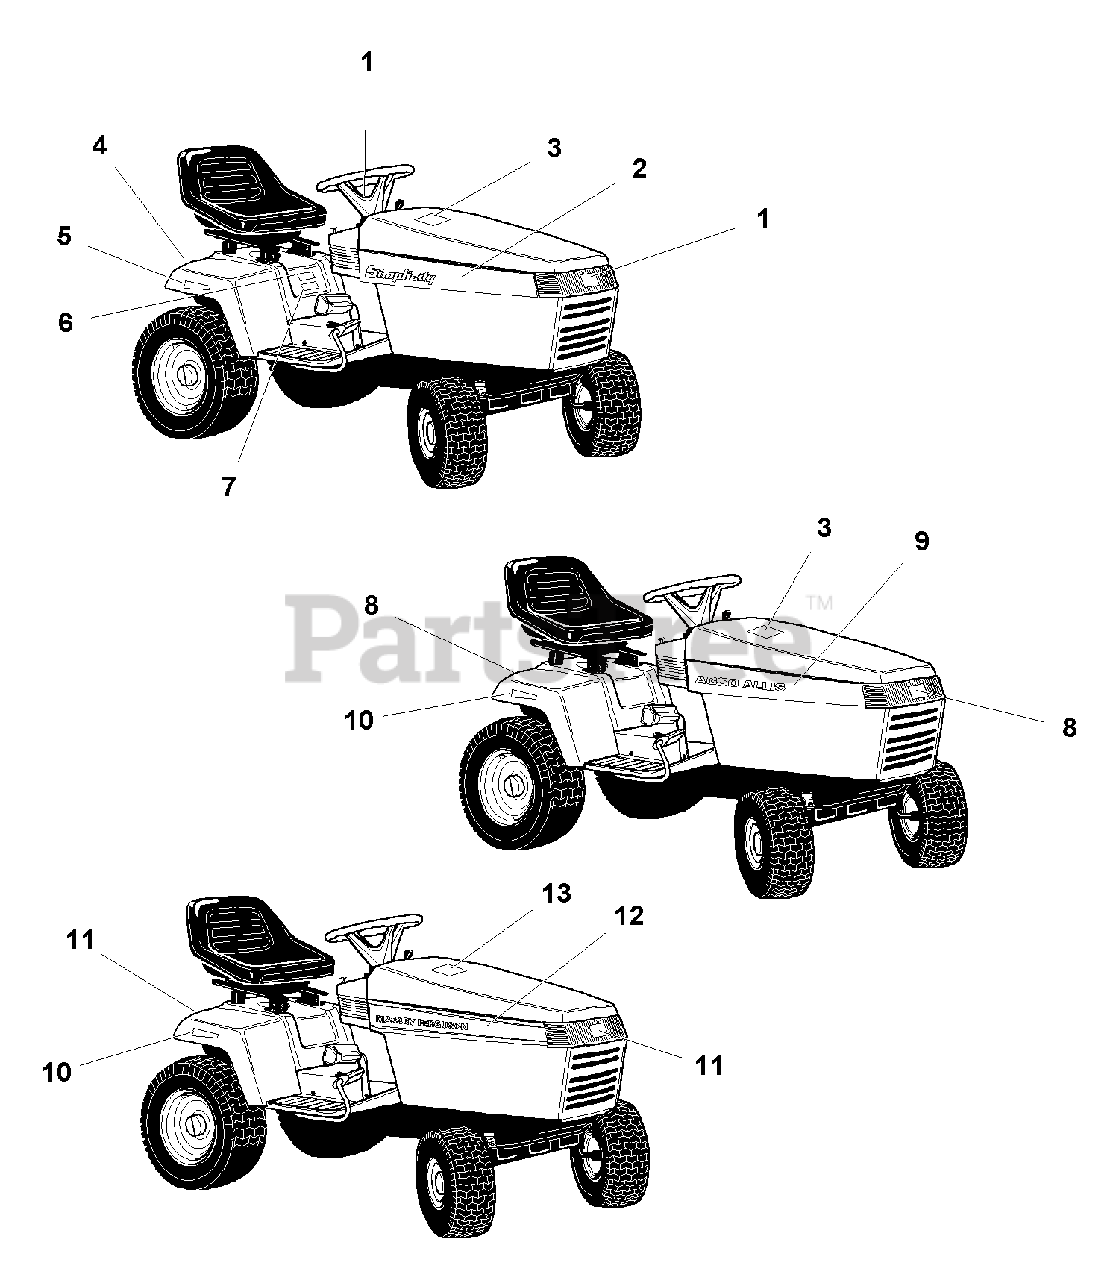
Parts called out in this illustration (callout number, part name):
1	DECAL, Simplicity Icon
2	DECAL, RH Hood, Simplicity
2	DECAL, LH Hood, Simplicity
3	DECAL, Paint, Simplicity & AGCO-Allis
4	DECAL, Simplicity Logo with Icon
5	DECAL, Controlled Traction, Simplicity
6	DECAL, Seat Deck, Broadmoor, Simplicity
7	DECAL, Model, Simplicity Broadmoor - Hydro 16 HP
7	DECAL, Model, Simplicity Broadmoor - Hydro 14V-Twin
7	DECAL, Model, Simplicity Broadmoor - Hydro 16V-Twin
7	DECAL, Model, Simplicity Broadmoor - Hydro 18V-Twin
8	DECAL, AGCO-Allis Icon
9	DECAL, LH Hood - AGCO-Allis 1615H
9	DECAL, RH Hood - AGCO
9	DECAL, LH Hood - AGCO
9	DECAL, RH Hood - AGCO-Allis 1618VH
9	DECAL, LH Hood - AGCO-Allis 1618VH
9	DECAL, RH Hood - AGCO-Allis 1615H
9	DECAL, LH Hood - AGCO-Allis 1614VH
9	DECAL, RH Hood - AGCO-Allis 1614VH
9	DECAL, RH Hood - AGCO-Allis 1616VH
9	DECAL, LH Hood - AGCO-Allis 1616VH
10	DECAL, Controlled Traction, AGCO-Allis & Massey Ferguson
11	DECAL, Massey Ferguson Icon
12	DECAL, LH Hood, Massey Ferguson 2616H
12	DECAL, RH Hood, Massey Ferguson 2616H
12	DECAL, LH Hood, Massey Ferguson 2615H
12	DECAL, RH Hood, Massey Ferguson 2615H
12	DECAL, LH Hood, Massey Ferguson 2618H
12	DECAL, RH Hood, Massey Ferguson 2618H
13	DECAL, Paint, Massey Ferguson
